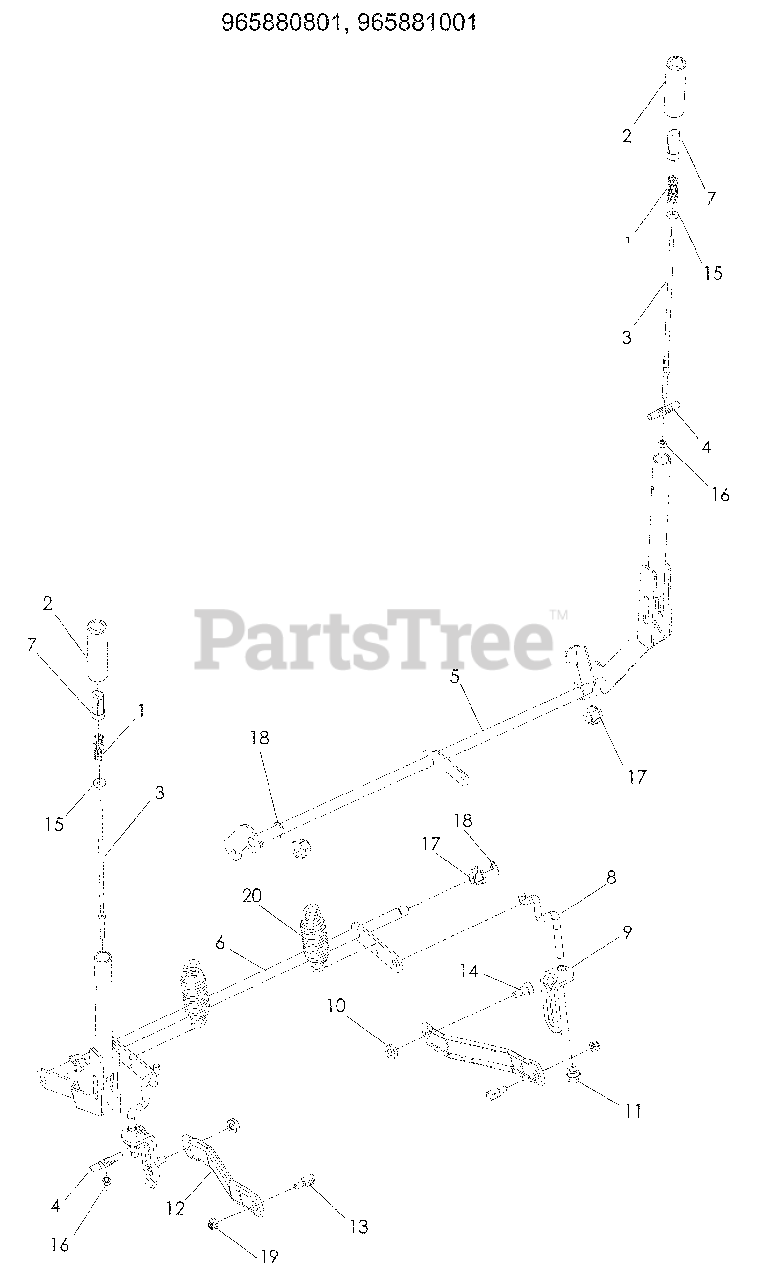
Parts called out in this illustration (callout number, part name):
1	SPRING, COMPRESSION
2	GRIP, HANDLE
3	ROD, HANDLE RELEASE
4	ROD, LATCH RELEASE
5	SHAFT, BRAKE
6	SHAFT, LIFT
7	BUTTON, PUSH
8	LINK, REAR SUSPENSION
9	BRACKET, CENTERING LNK
11	NUT, LIFT LINK
12	ARM, SUSPENSION RR
13	STUD, w/ANTI- ROTATE
14	BOLT 3/8-16 x 3/8 SKT HD
15	WASHER ¼ FLAT
16	NUT ¼-20 HEX NYLOC
17	PLASTIC NUT
19	NUT 5/16-18 FLANGE NYLOC
